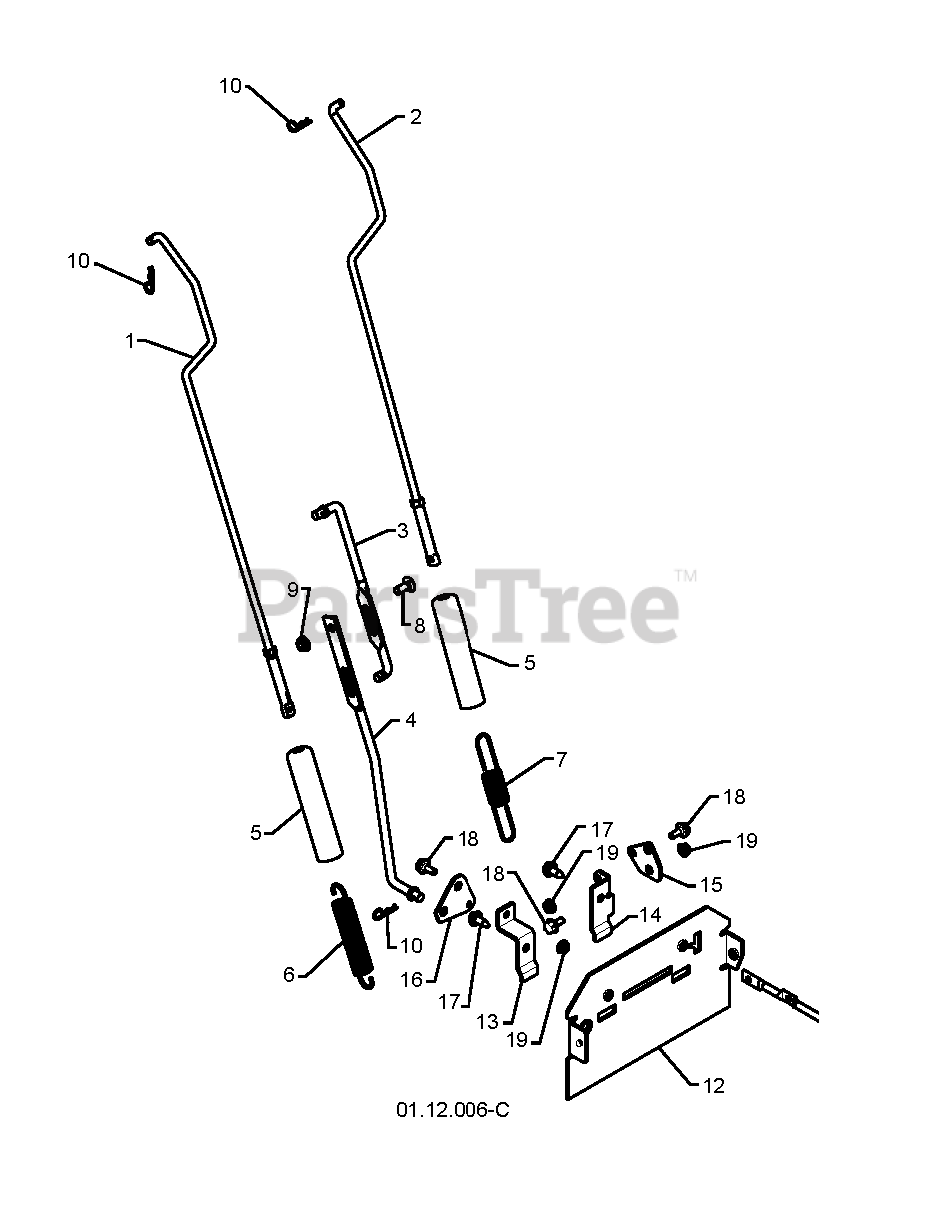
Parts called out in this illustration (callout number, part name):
1	ROD.ASM.IMPELLER
2	ROD.ASM.TRACTION
3	ROD, UPPER SPEED CONTROL
4	ROD, LOWER SPEED CONTROL.SNOW
5	SLEEVE, SPRING
6	SPRING, AUGER CONTROL
7	SPRING, TRACTION DRIVE
8	BOLT
9	NUT.FLANGE.5/16
10	SPRING RETAINER
11	ROD.CLUTCH.YELLOW.ZINC(VT)
12	PLATE.REAR
13	RP BRACKET.SHIFTER.PLATE.BZP
14	BRACKET.CLUTCH.PLATE.BZP
15	PLATE
16	PLATE.SHIFTER.BZP
17	SELF-TAPPING SCREW 5/16-18X3/4
18	BOLT.SHOULDER.3/X.25
19	NUT.HEX.FLANGE.1/4
